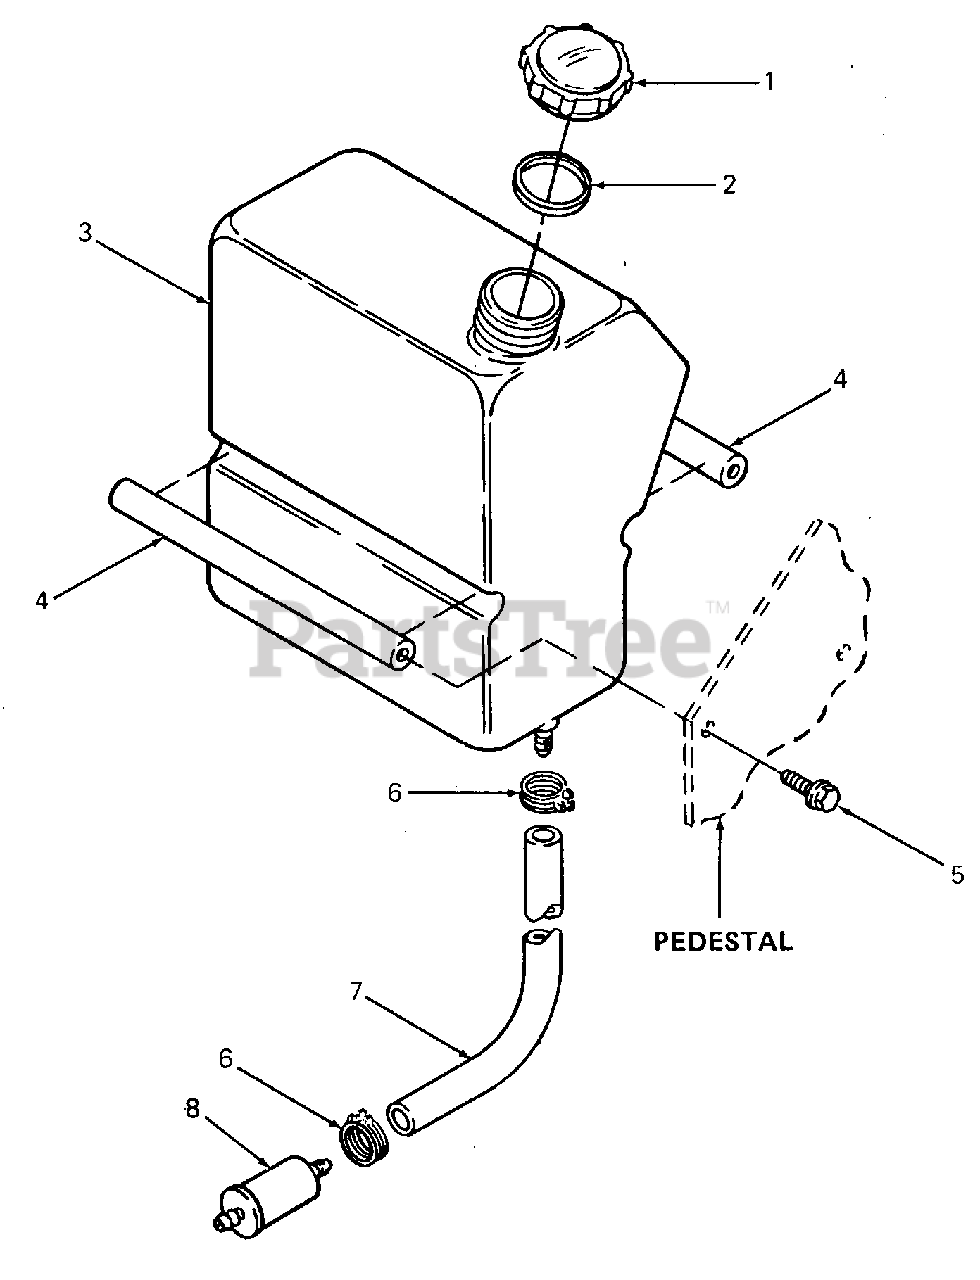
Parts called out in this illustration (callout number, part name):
1	Cap, Fuel
2	Gasket, Fuel Tank Cap
3	Tank, Fuel
4	Tube, 11.27 Lg
5	Screw, Hex Wash Hd B Tapp, 5/16-18 X .50 Lg
6	Clamp, Hose
7	Line, Fuel, 22 in. Lg
8	Filter, Fuel
